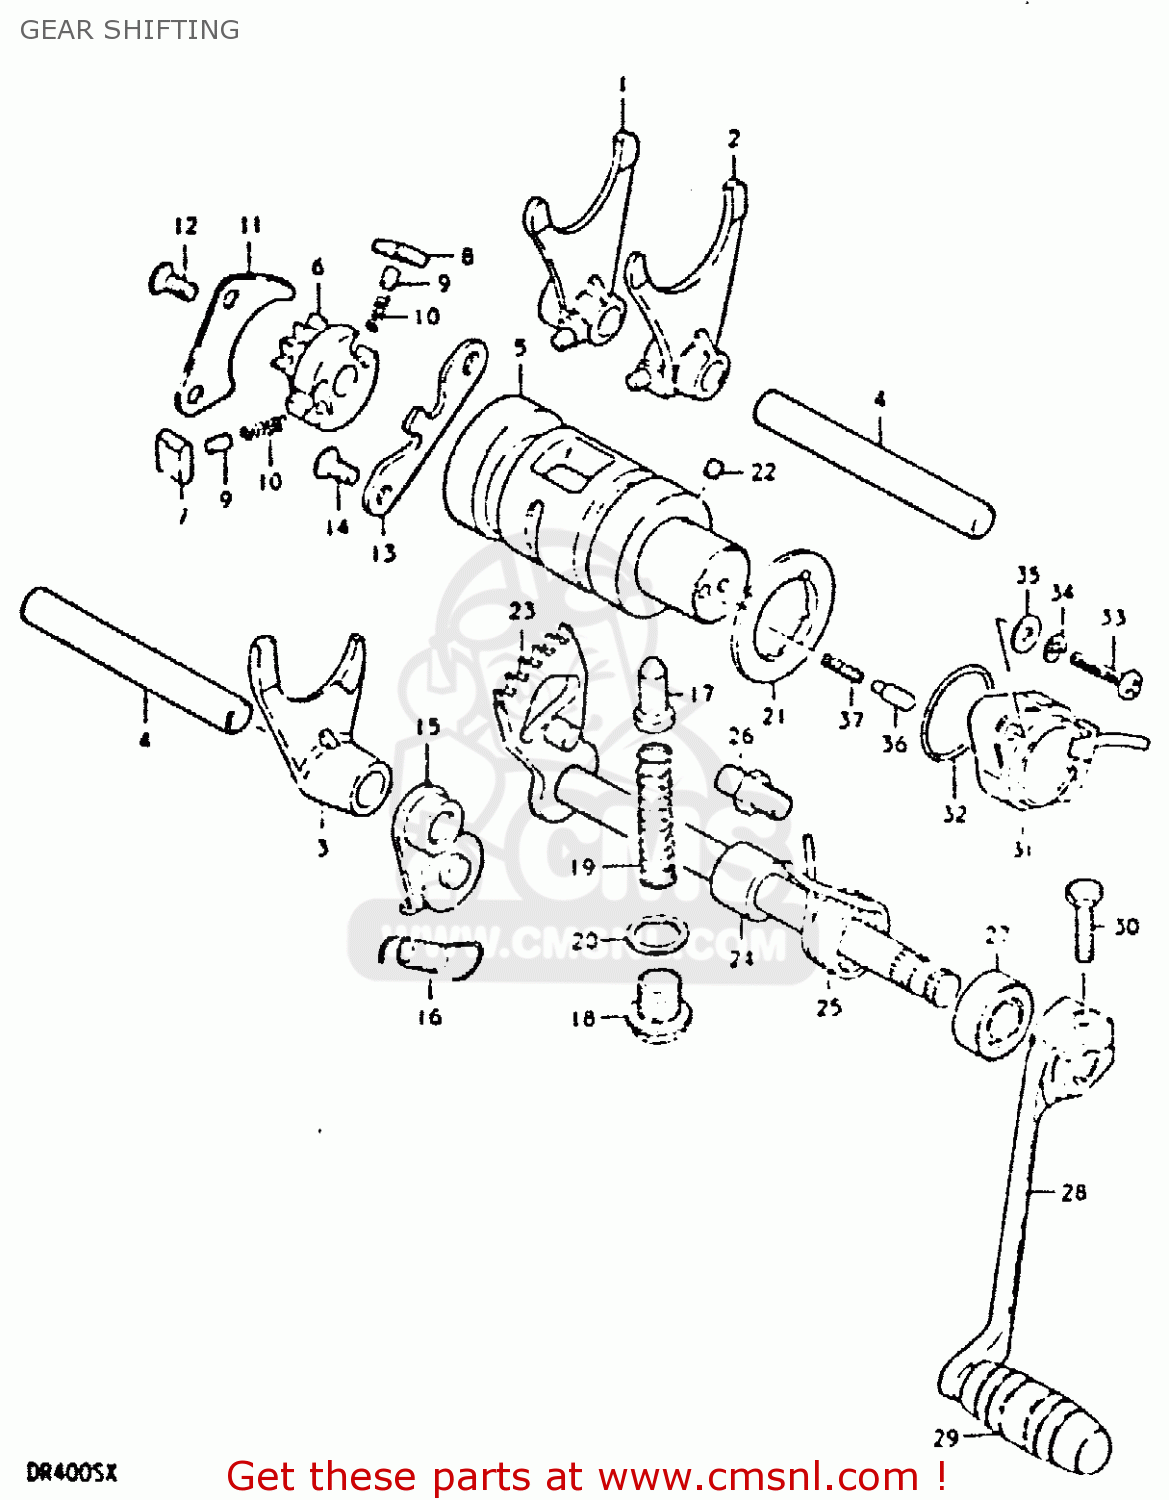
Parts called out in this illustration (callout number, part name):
1	FORK,GEAR SHIFT NO.1
2	FORK,GEAR SHIFT
3	FORK,GEAR SHIFT NO.3
4	SHAFT,GEAR SHIFT FORK
5	CAM,GEAR SHIFT
6	RETAINER,GEAR SHIFT CAM
7	PAWL,GEAR SHIFT NO.1
8	PAWL,GEAR SHIFT NO.2
9	PIN(5X8)
10	SPRING
11	LIFTER,GEAR SHIFT PAWL
12	SCREW
13	GUIDE,GEAR SHIFT CAM
14	SCREW
15	STOPPER,GEAR SHIFT CAM
16	SPRING
17	STOPPER,GEAR SHIFT CAM NO.2
18	PLUG
19	SPRING
20	GASKET(14X19.2X2) (NAS)
21	PLATE,GEAR SHIFT CAM STOPPER
22	PIN 4X6
23	SHAFT,GEAR SHIFT
24	SPACER(12X20X15.3)
25	SPRING
26	STOPPER,GEAR SHIFT CAM
27	OIL SEAL
28	LEVER ASSEMBLY,GEAR SHIFTING
29	RUBBER,GEAR SHIFT PEDAL
30	BOLT
31	TERMINAL BASE,NEUTRAL SWITCH
32	O-RING (D:2.4 ID:26.2)
33	SCREW 5X20
34	LOCK WASHER
35	WASHER
36	PIN(5X15.5)
37	SPRING
